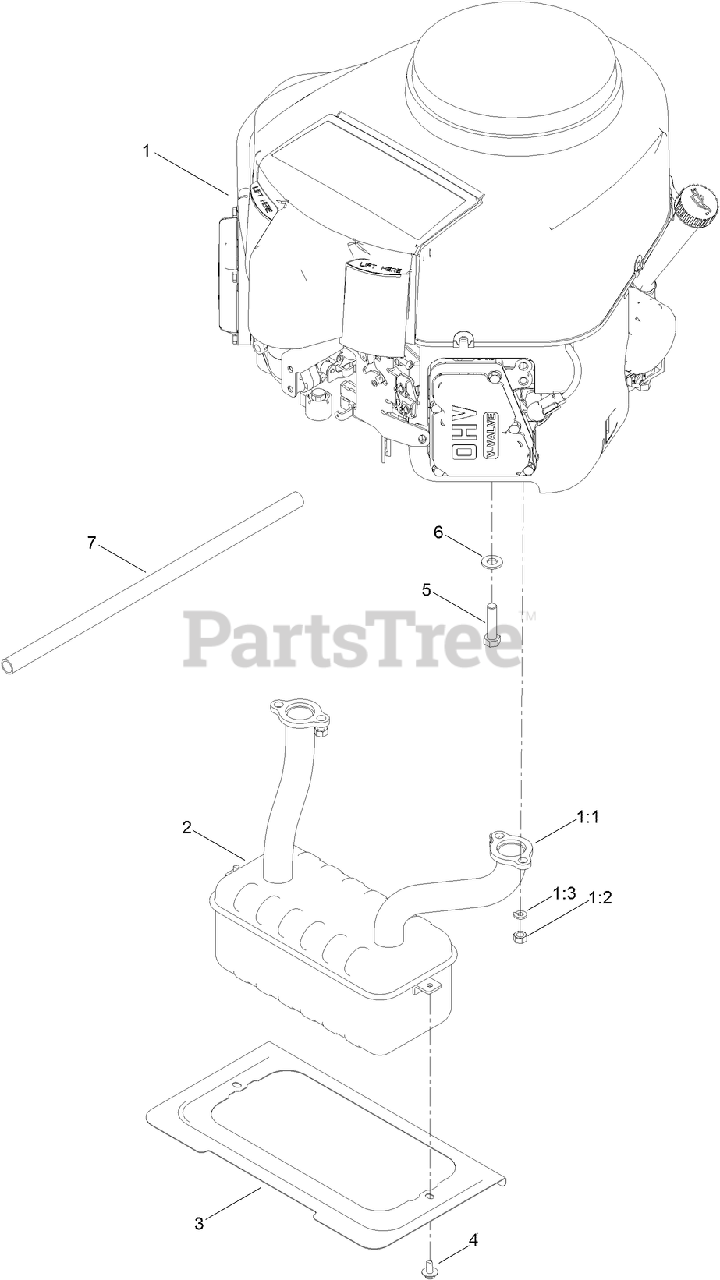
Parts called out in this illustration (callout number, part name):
1:1	GASKET-EXHAUST
1:3	WASHER-LOCK
2	MUFFLER
3	SHIELD-HEAT
4	SCREW-HHFTF
5	BOLT-HH
6	WASHER-FLAT
7	TUBE-DRAIN, OIL
